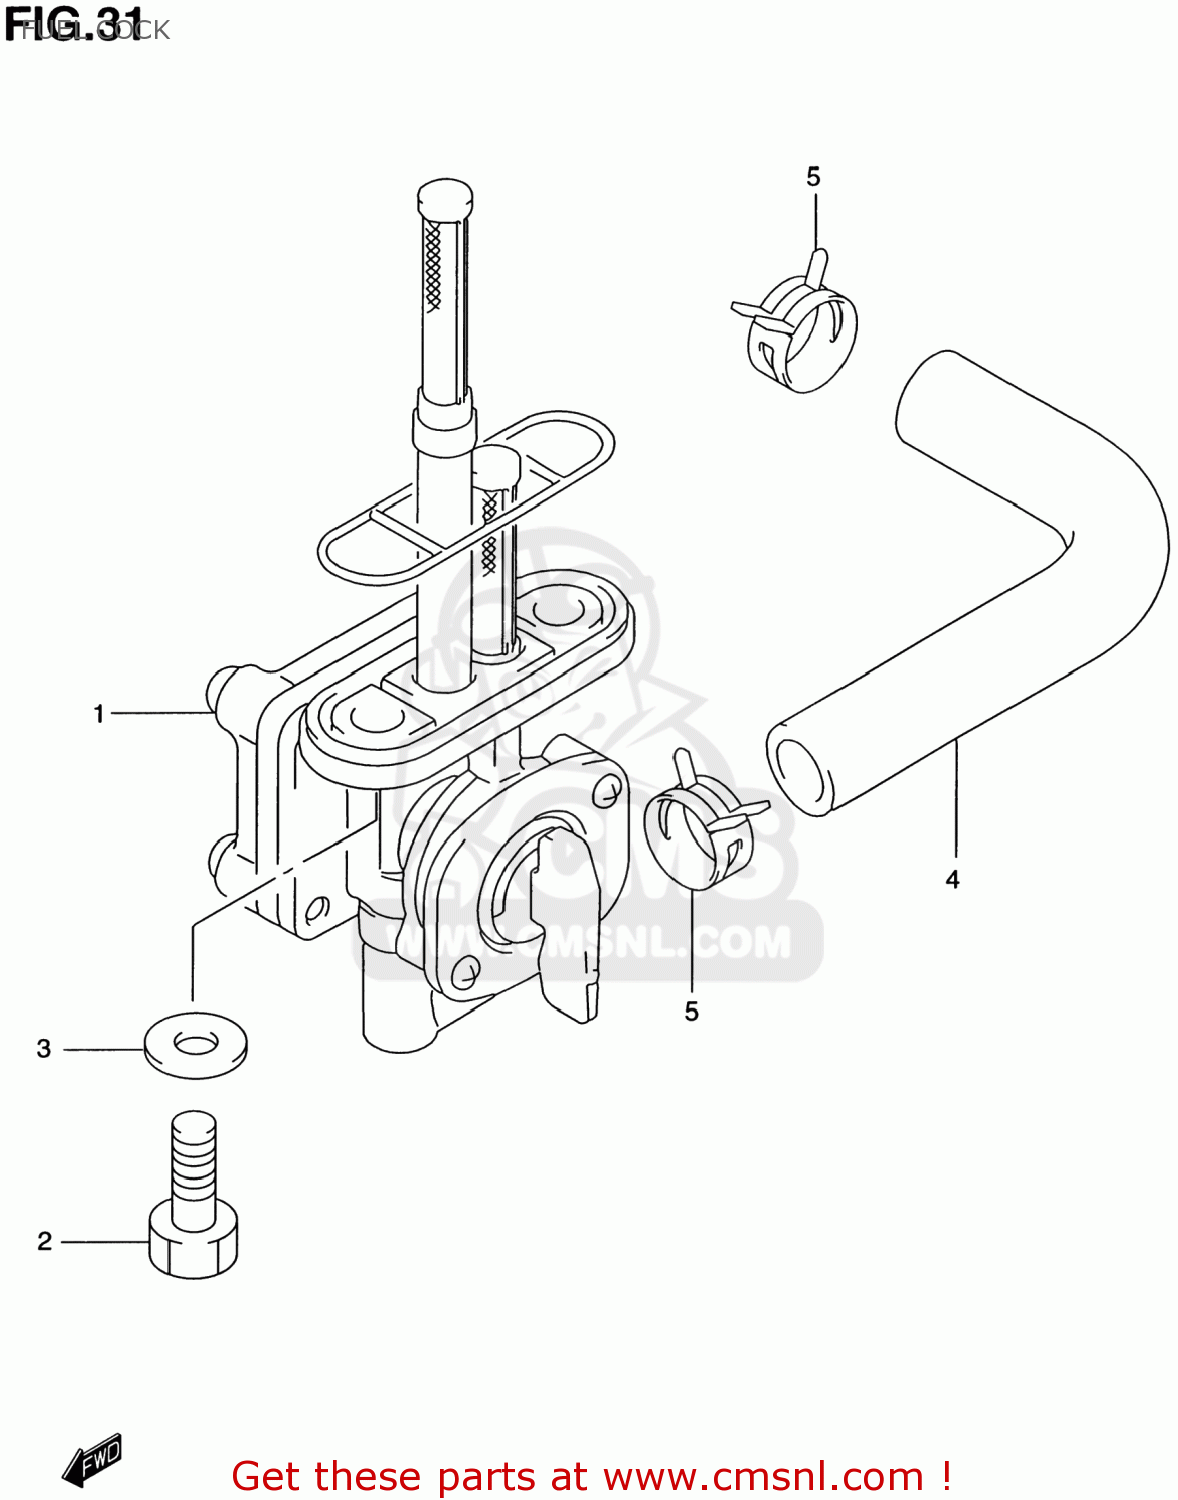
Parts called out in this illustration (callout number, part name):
1	COCK ASSY,FUEL
2	BOLT(6X20)
3	GASKET(6.4X11.5X0.8) (NAS)
4	HOSE(7X12X600)
5	CLIP
